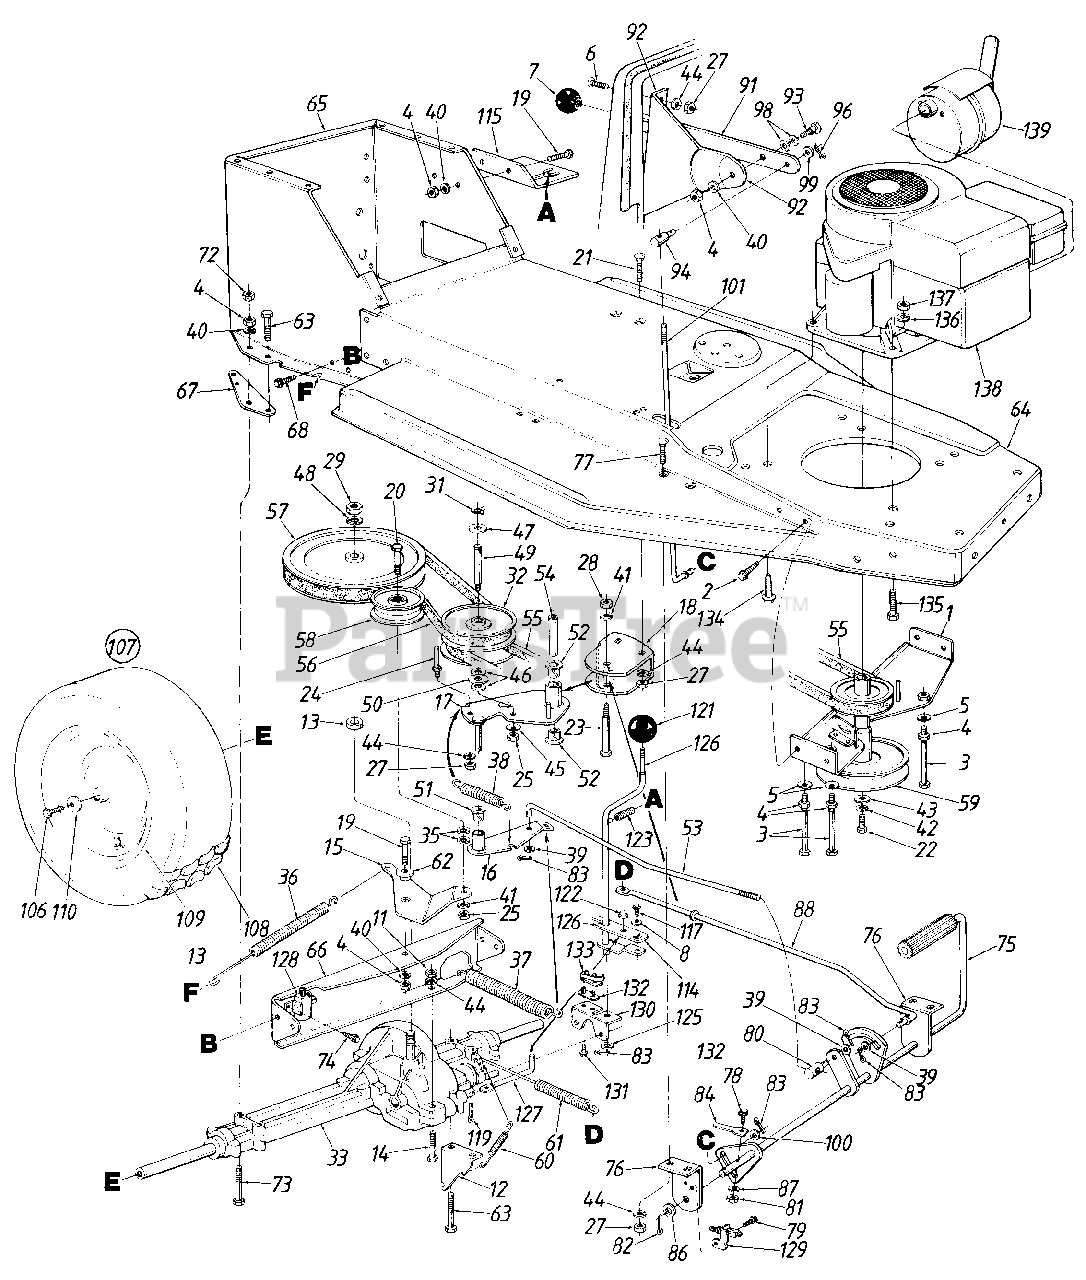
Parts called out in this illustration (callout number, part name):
1	Engine Pulley Belt Guard Ass'y.
2	Hex AB-Tap Scr. 1/4 X .62"
3	Hex Bolt 5/16-18 X 5 1/4" Lg.
4	Hex Nut 5/16-18 Thd.
5	Bell-Wash. .345" I.D. x .88
6	Truss-Mach. Scr. 1/4-20 x .50" Lg.
7	Gear Shift Knob
8	Bell-Wash. .265" I.D. x .75
11	Hex Nut 1/4-28 Thd.
12	Spring Retainer Brkt.
13	Spacer .5" I.D. x .93"
14	Hex Bolt 1/4-28 x 1.75" Lg.
15	Idler Bracket
16	Variable Speed Torque Brkt. Ass'y.
17	Variable Speed Brkt. Ass'y.
18	Variable Speed Pivot Brkt.
19	Hex Bolt 5/16-18 X .75" Lg.
20	Hex Bolt 3/8-24 X 1 3/4" Lg. Gr. 5
21	Carr. Bolt 1/4-20 x .75" Lg.
22	Hex Bolt 7/16-20 x 1.5" Lg.
23	Hex Bolt 3/8-16 X 2.5" Lg.
24	Belt Guard Pin
25	Hex Nut 3/8-24 Thd.
27	Hex Nut 1/4-20 Thd.
28	Hex Nut 3/8-16 Thd.
29	Hex Jam Nut 1/2-20 Thd.
31	Snap Ring
32	Variable Speed Pulley Ass'y.
33	Transaxle Complete
35	Fl-Wash. 3/8" I.D. x I"
36	Extension Spring 6.12" Lg.
37	Extension Spring 7.5" Lg.
38	Extension Spring 2.59" Lg.
39	Fl-Wash. .385" I.D. x .620"
40	L-Wash. 5/16" I.D.
41	L-Wash. 3/8" I.D.
42	L-Wash. 7/16" I.D.
43	Fl-Wash. .450" I.D. x 1.25"
44	L-Wash. 1/4" I.D.
45	Bell-Wash. .39" I.D. x 1.13"
46	Fl-Wash. .56" I.D. x 1.0" O.D.
47	Washer "Teflon" .565 I.D.
48	L-Wash. 72" I.D.
49	Shaft .56" Dia. x 3.875" Lg.
50	Thrust Brg. 1.25 O.D.
51	Flanged Nyliner Brg.
52	Nyliner Flanged Brg.
53	Speed Control Link
55	V-Belt
56	V-Belt
57	1/2 V-Pulley .500" I.D. x 8.00"
58	Idler Pulley 3-1/8" Dia.
59	Dbl. Pulley 6.0" Dia. x 3.56"
60	Extension Spring 3.18" Lg.
61	Extension Spring 7.08" Lg.
62	Shld. Spacer .500" Dia.
63	Hex Bolt 5/16-18 x 2.75" Lg.
64	Front Frame
65	Rear Frame
66	Transaxle Support Brkt.
72	Hex L-Nut 5/16-18 Thd.
73	Hex Bolt 5/16-18 x 3.0" Lg.
74	Truss Mach. B-Tap Scr. #10 0 x.50" Lg.
75	Clutch/Brake Pedal Ass'y.
76	Clutch/Brake Pedal Mounting Brkt.
77	Carr. Bolt 1/4-20 x .62" Lg.
78	Hex Bolt 1/4-20 x 1.0" Lg.
79	Hex TT-Tap Scr. 1/4-20 x .5"
80	Ferrule
82	Cot-Pin 3/32" Dia. x 1.0" Lg.
83	Cot-Pin 3/32" Dia. x .75" Lg.
84	Switch Actuator
86	Fl-Wash. .635" I.D. x 1.0"
91	Speed Selector Lever
92	7 Speed Selector Brkt.
93	Shld. Bolt .437" x .35
94	Ferrule
96	Intern. Cot-Pin 5/16" Dia.
98	Wave Wash. .445" I.D.
99	Fl-Wash. .344" I.D. x .62"
100	Fl-Wash. .25" I.D. x .62" O.D.
101	Speed Control Rod
106	Hex L-Bolt 5/16-24 x .75" Lg.
107	Rear Wheel Ass'y. Comp.
110	Bell-Wash. .345" I.D. x .88"
114	Shift Lever Adjusting Link
115	Shift Lever Spring Brkt.
117	Hex Bolt 1/4-20 x .50 Lg.
119	Intern. Cotter Pin
121	Ball Knob
122	Retaining Ring
123	Compression Spring 1.5" Lg.
125	Fl-Wash. .469" I.D. x .88"
126	Shift Rod Ass'y.
127	Shift Rod
128	Safety Switch
129	Safety Switch
130	Shift Lever Support
131	Hex Wash. Hd. AB-Tap Scr. #8 x .5" Lg.
132	Insulator Nut Plate
133	Spring Switch
134	Hex Wash. Hd. Tap Scr. 3/8-16 x 1.25" Lg.
135	Hex Bolt 5/16-24 x 1-1 /4" Lg. Grade 5
136	L-Wash. 5/16" I.D.
137	Hex Nut 5/16-24 Thd.
138	Engine
